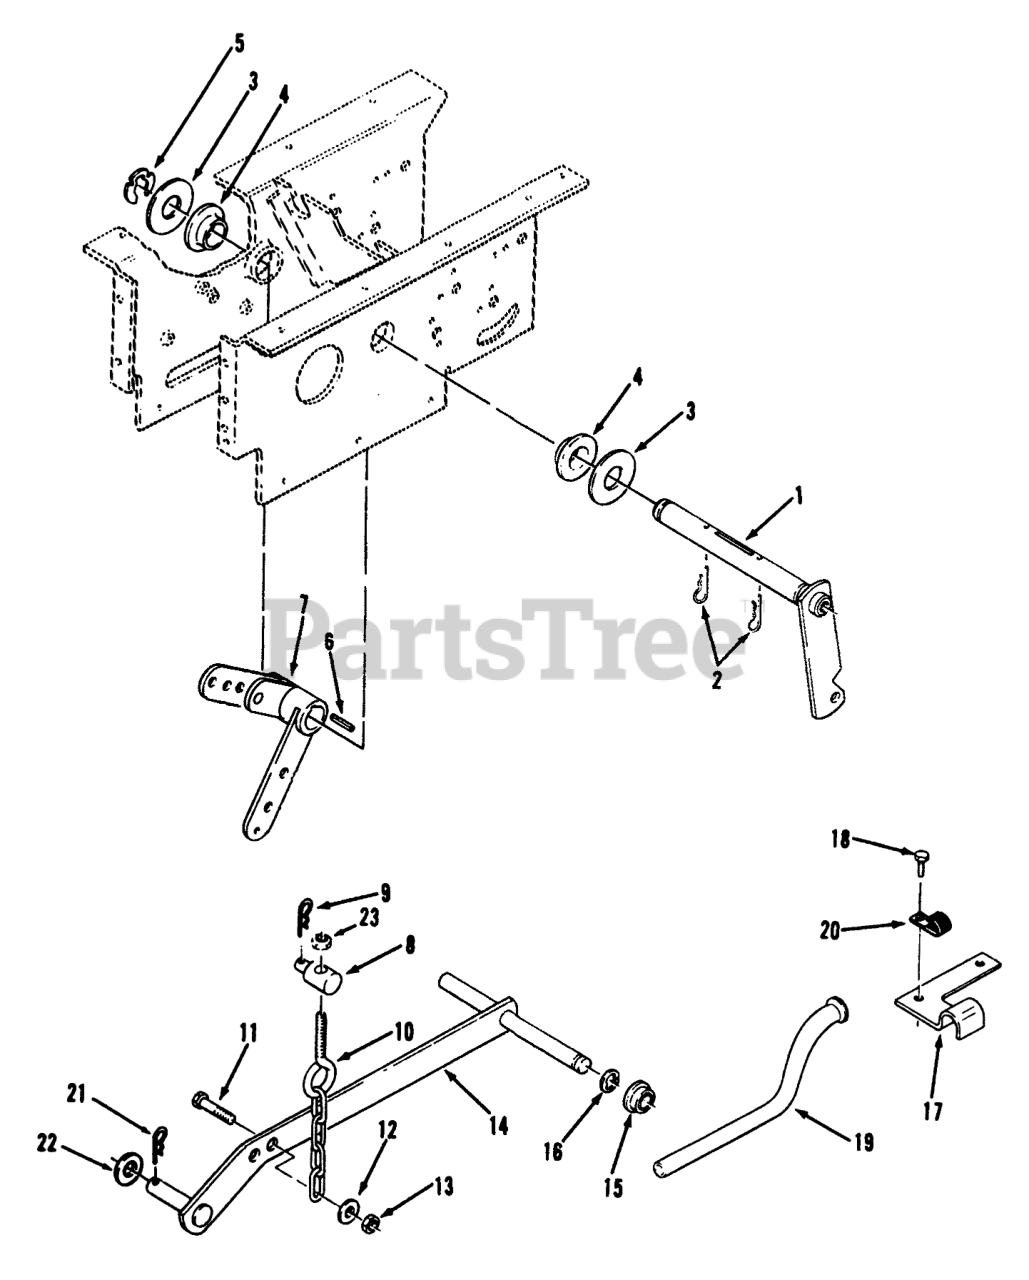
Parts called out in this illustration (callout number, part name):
1	WLDMT-LIFT ARM
2	Pin-Cotter
3	WASHER-FLAT
4	BEARING-FLANGE
5	Retainer
6	KEY-SQUARE
7	LIFT LEVER ASM
8	TRUNNION-LIFT
9	Hairpin Cotter
10	CHAIN-LIFT
11	SCREW-HH
12	WASHER-PLAIN
13	NUT-LOCK, NI
14	Bar-Lift
15	BUSHING
16	E Ring
17	CLAMP-CONDUIT R
18	SCREW-HH, LOCK
19	TUBE-CONDUIT R
20	CLIP
21	Hairpin Cotter
22	WASHER-FLAT
23	NUT-LOCK, NI
